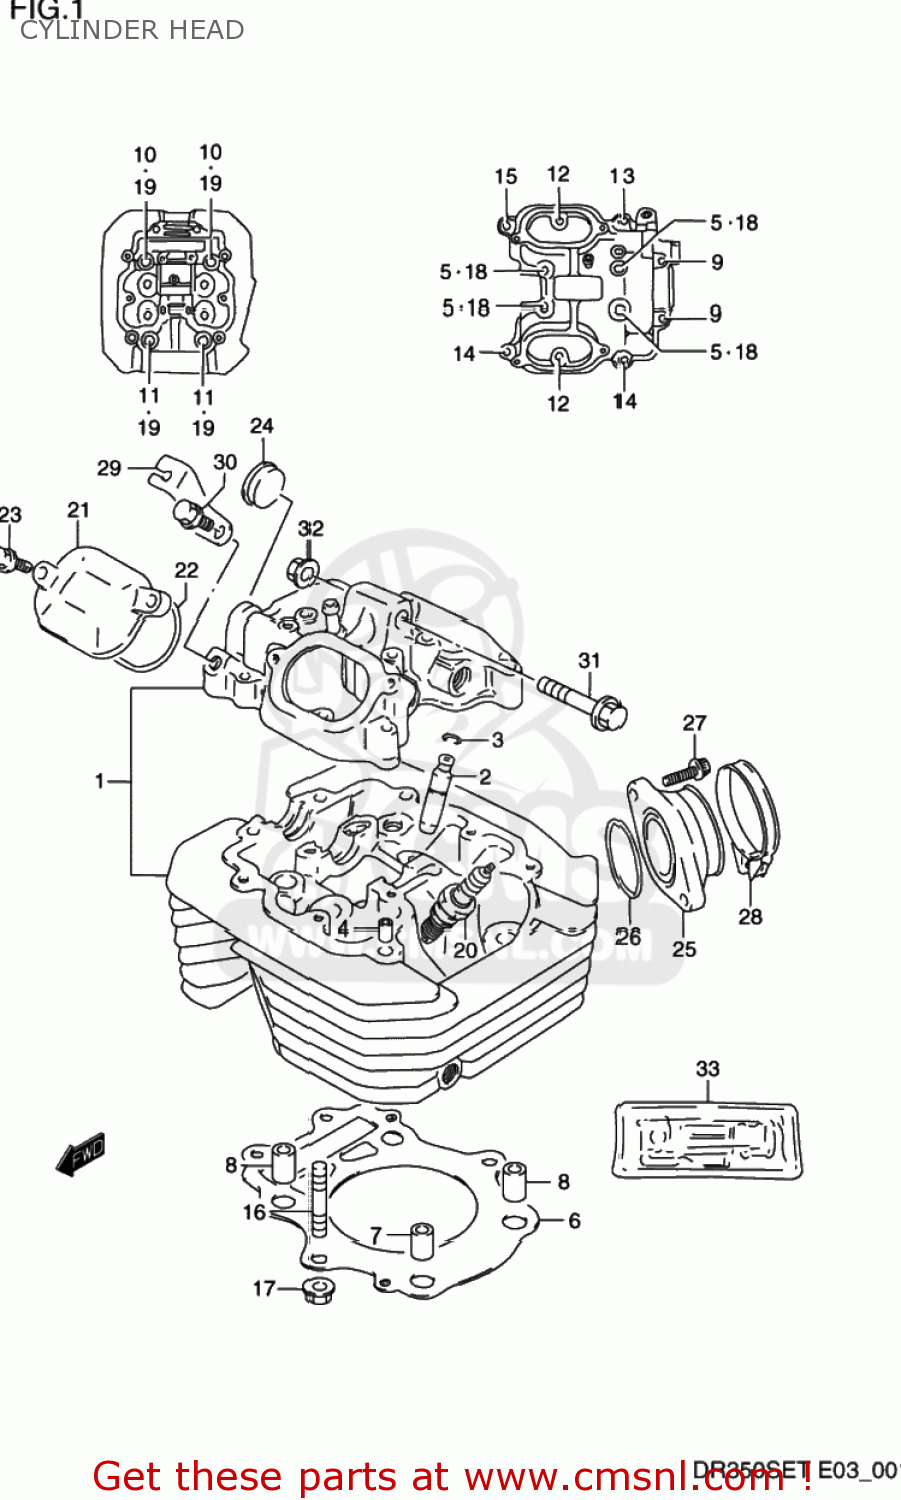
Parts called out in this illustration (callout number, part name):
1	HEAD ASSEMBLY,CYLINDER
2	GUIDE,VALVE
3	RING,SNAP
4	PIN(6.2X8X11)
5	BOLT(6X55)
6	GASKET,CYLINDER HEAD (NAS)
7	PIN
8	PIN(10.4X13X22)
9	BOLT(6X115)
10	BOLT(10X180)
11	BOLT(10X155)
12	BOLT
13	BOLT
14	BOLT(6X35)
15	BOLT(6X39)
16	BOLT,STUD
17	NUT
18	GASKET(5.8X13X1.2) (NAS)
19	WASHER (10.5X22X2.3)
20	PLUG,SPARK(CR9EK)
21	CAP,INSPECTION
22	GASKET (NAS)
23	BOLT
24	PLUG,OD:30
25	PIPE,INTAKE
26	O RING(D:2.4,ID:39.7)
27	BOLT
28	CLAMP
29	LEVER,DECOMP SHAFT RH
30	BOLT, LOWER
31	BOLT(8X65)
32	NUT
33	GASKET SET (NAS)
